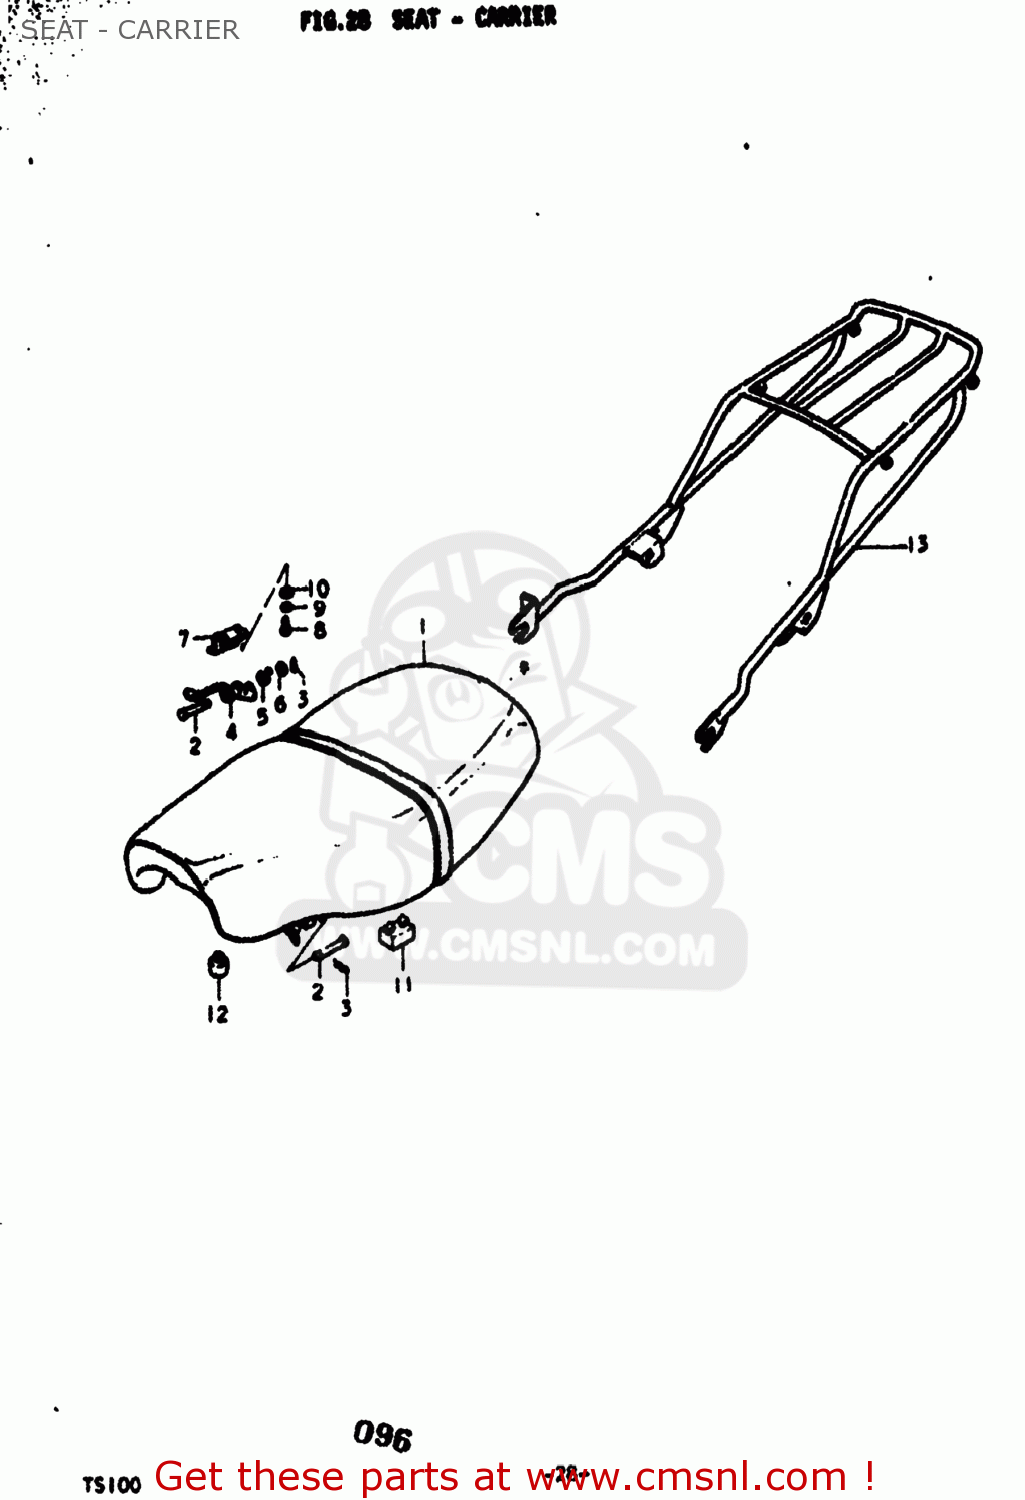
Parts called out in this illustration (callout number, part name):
1	SEAT ASSEMBLY
2	PIN
3	CLIP
4	STRIKER,SEAT LOCK
5	SPRING
6	WASHER
7	PLATE,SEAT CLAMP GUIDE
8	BOLT
9	LOCK WASHER
10	WASHER
11	CUSHION
12	CUSHION
13	CARRIER
